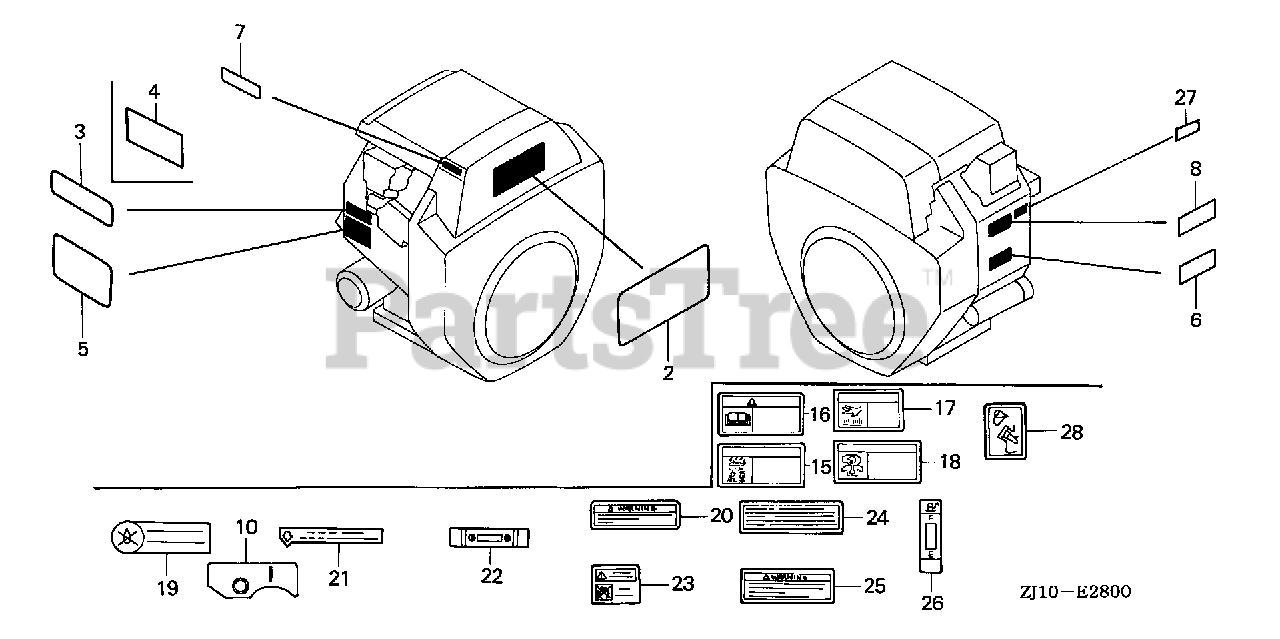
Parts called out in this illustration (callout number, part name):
2	EMBLEM (GX620)
3	LABEL, SPECIFICATION (GX620)
5	LABEL, CAUTION
